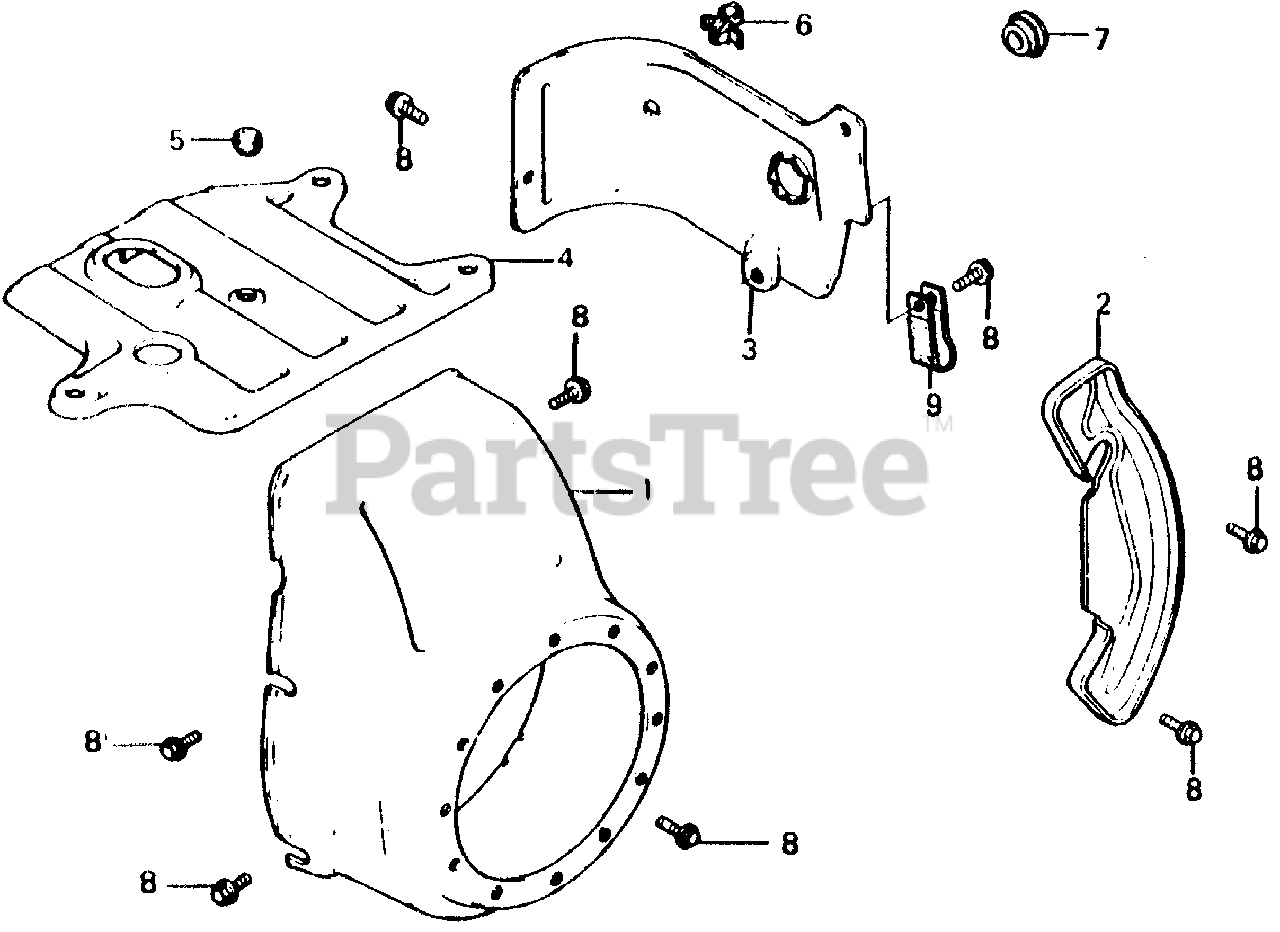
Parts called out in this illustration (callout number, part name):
1	COVER, FAN *R8* (BRIGHT RED)
2	PLATE, SIDE
4	COVER, TOP
5	GROMMET, TOP COVER
6	CLIP, IGNITION WIRE (8MM)
7	GROMMET, DRAIN HOLE
8	BOLT, FLANGE (6X12) (CT200)
9	CLIP, CABLE
